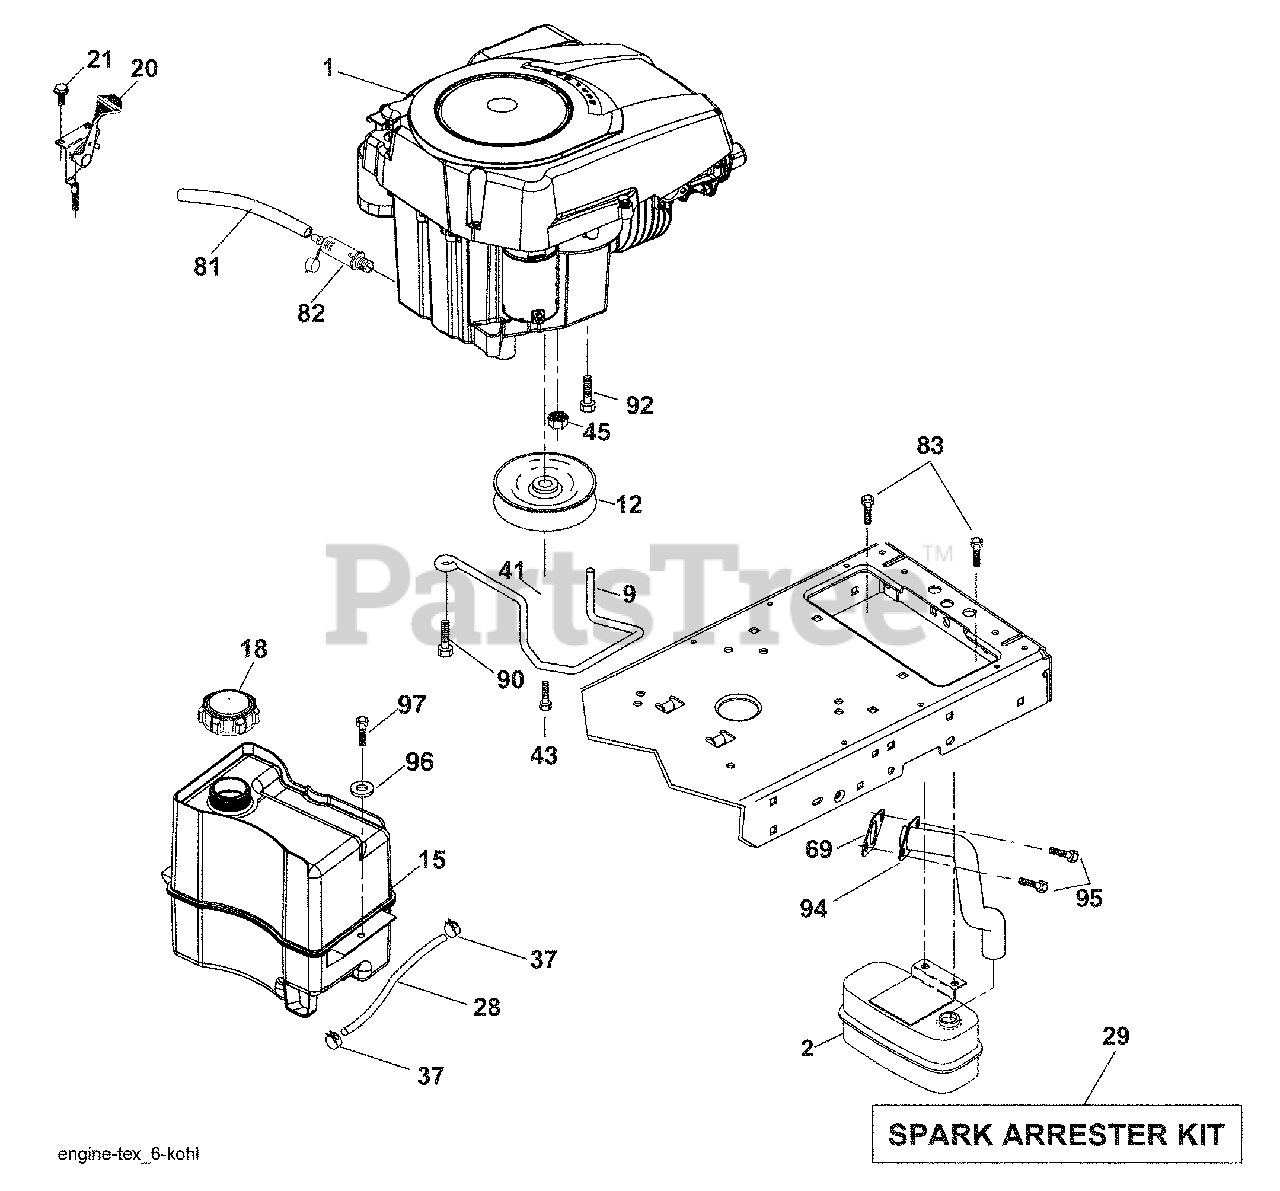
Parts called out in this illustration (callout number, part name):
9	Keeper Belt Engine
12	Pulley Engine
15	Tank Fuel 1.5
18	Cap Asm
20	Control Throttle
21	Screw 10 x 3/4 Single Lead-Hex
28	Fuel Line
29	Spark Arrester Kit
37	Clamp Hose
42	Washer Lock 7/16
43	Bolt Hex 7/16-20 x 4 Gr. 5
45	Nut Keps Hex 1/4-20 unc
69	Gasket
81	Tube Drain Oil Easy
82	Plug Drain Oil
83	Bolt 5/16-18 unc x 3/4 w/Sems
90	Screw 3/8-16 x 1
92	Screw 3/8-16 x 1
94	Tube Exhaust
95	Screw 5/16-18 x .75
96	Washer 9/32 x 7/8 x 16 Ga.
97	Screw 1/4-20 x 3/4
